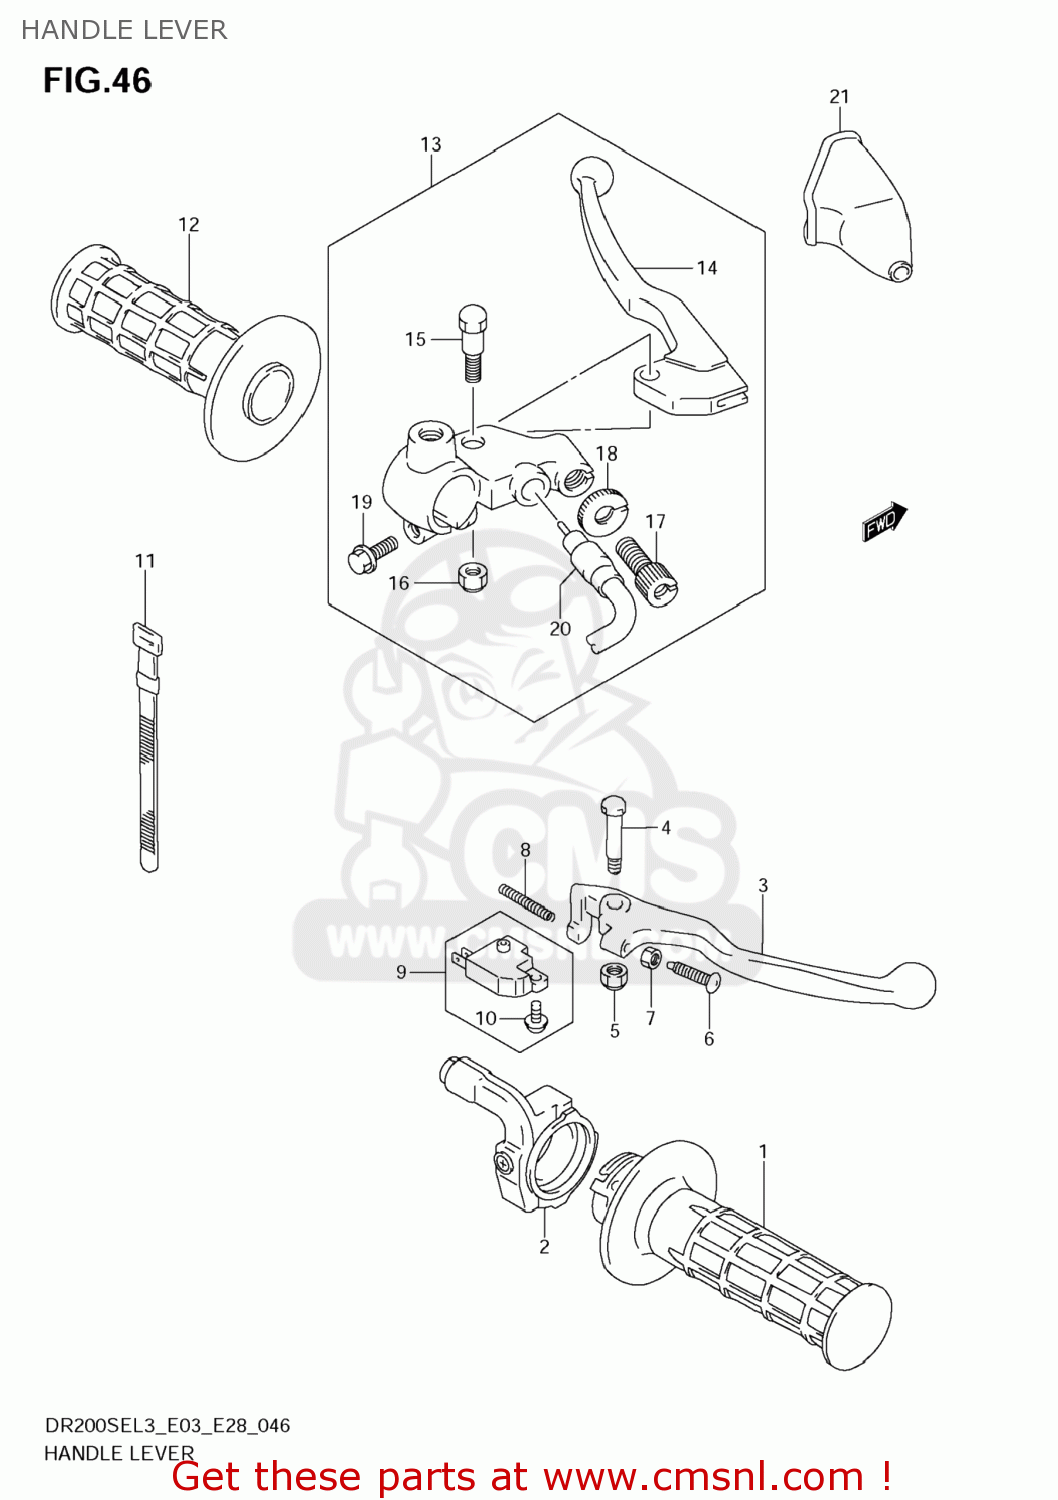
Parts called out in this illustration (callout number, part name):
1	GRIP,THROTTLE
2	CASE ASSY,THROTTLE
3	LEVER,BRAKE
4	BOLT,BRAKE LEVER
5	NUT
6	BOLT,ADJUST
7	NUT
8	SPRING,RETURN
9	SWITCH ASSY,FR BRAKE
10	SCREW
11	CLAMP(L:120)
12	GRIP,L
13	LEVER ASSY,CLUTCH
14	LEVER,CLUTCH
15	BOLT,LEVER PIVOT
16	NUT
17	ADJUSTER,WIRE
18	NUT,LOCK
19	BOLT
20	SWITCH ASSY,CLUTCH
21	COVER,CLUTCH CABLE DUST
